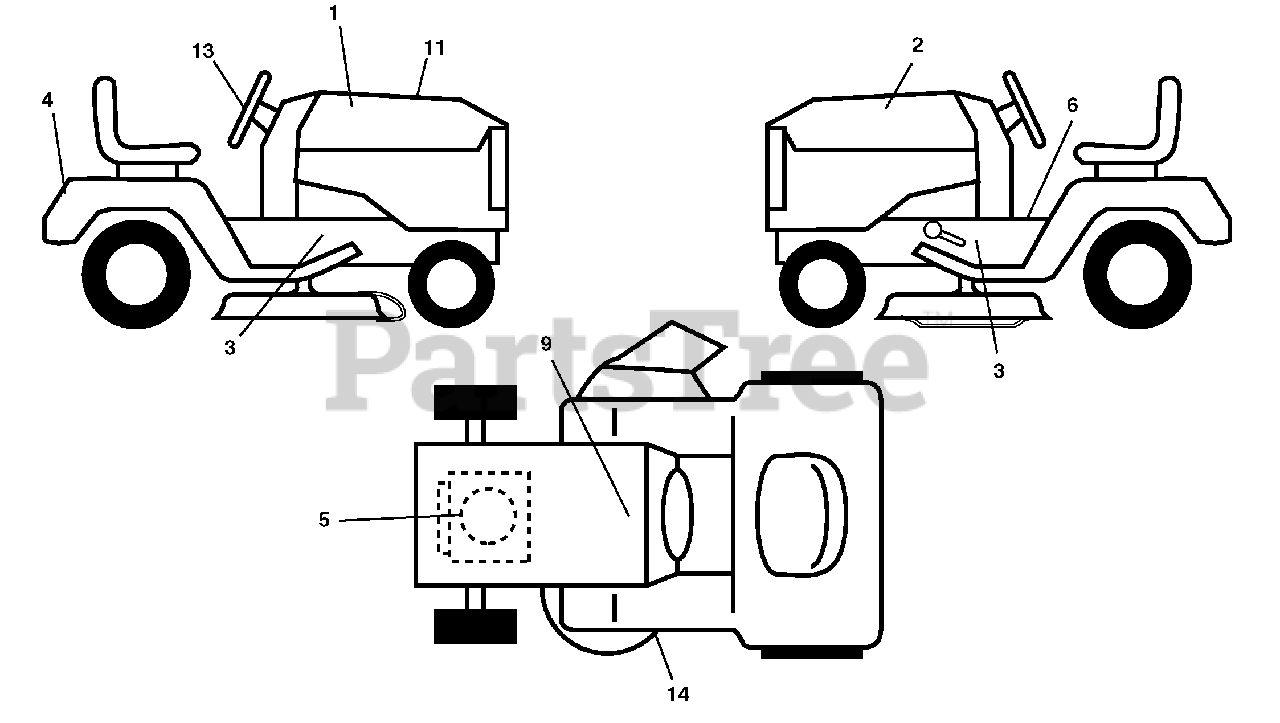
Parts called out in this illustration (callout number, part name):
1	Decal, Hood RH
2	Decal, Hood LH
3	Decal, Chassis
4	Decal, Fender
5	Decal, Engine
6	Decal, Fender Operator's
9	Decal, Battery Dnge/Poi
11	Decal, Replacement
13	Decal, Steering Wheel
14	Decal, Mower Schematic
14	Pad Foot Pedal Control
14	Decal, Bypass
14	Pad, Footrest, LH
14	Manual, Operator's E&SP
14	Manual, Parts
